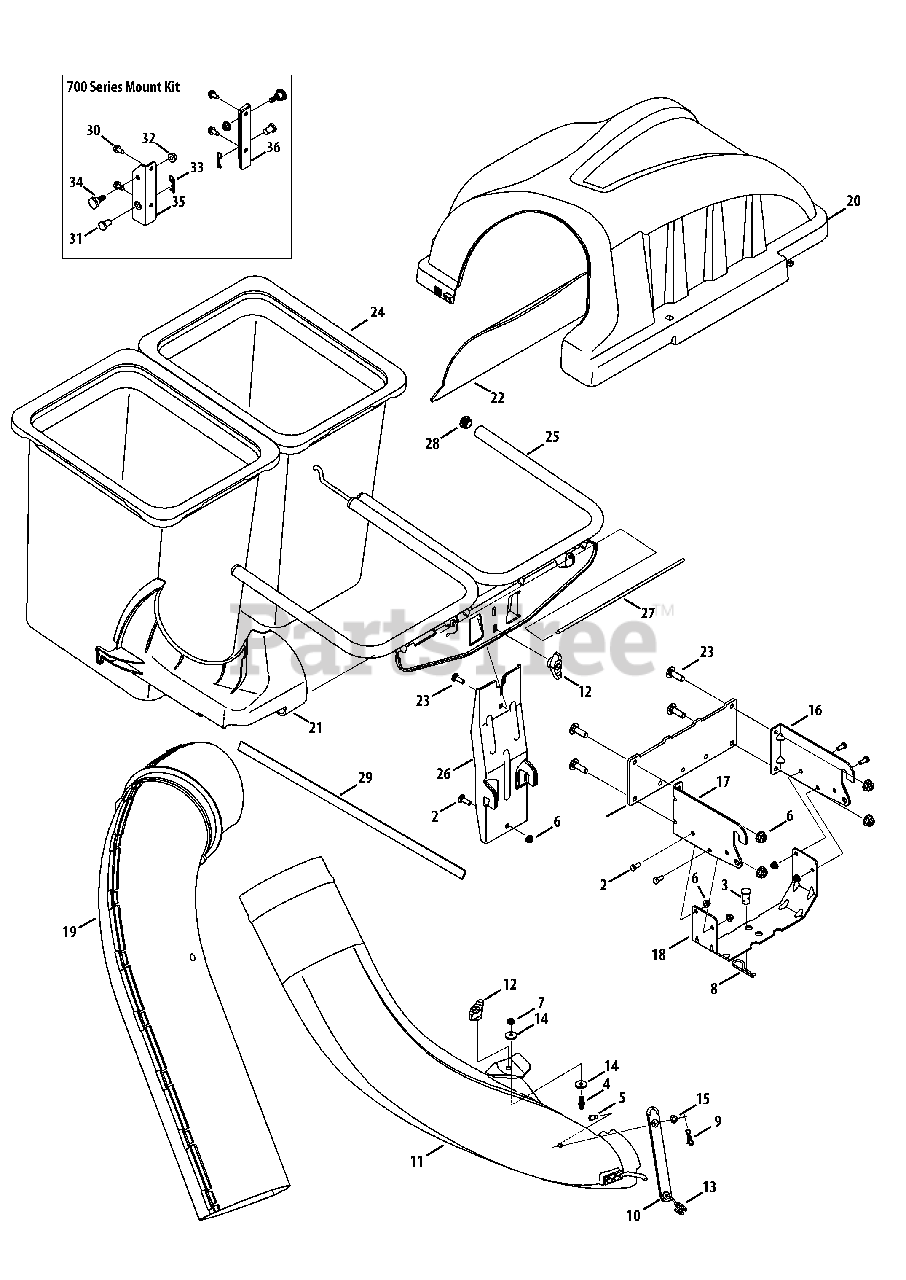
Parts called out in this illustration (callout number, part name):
1	Mounting Bracket Kit (Incl. ref. 16, 17)
2	Hex Head Screw, 5/16-18 x .75"
3	Clevis Pin, .62" Dia.
4	Attachment Pin, 1/4 x 0.66 Lg.
5	Clevis Pin, 5/16 x .75 Lg.
6	Flange Lock Nut, 5/16-18
7	Flange Lock Nut, 1/4-20
8	Internal Cotter Pin, .148 x 3.00
9	Bow-Tie Cotter Pin, 72
10	Chute Strap, 6.00 Lg.
11	Chute, Lower
11	Chute Rod, Lower
11	Screw-1/4-20 X .62
12	Wing Knob, 5/16-18
13	Torsion Spring Hook
14	Flat Washer, .265 x .938 x .120
15	Flat Washer, .344 x .62 x .033
16	Mounting Bracket, LH
17	Mounting Bracket, RH
18	Universal Bracket Support
19	Upper Discharge Chute
20	Double Bagger Cover Assembly
21	Upper Chute Support
22	Bagger Cover Screen
23	Carriage Screw, 5/16-18 x 1.00"
24	Grass-bag Assembly
25	Double Bag Support Assembly
26	Vertical Support Bracket
27	Cover Hinge Pin
28	End Plug
29	Self-Adhesive Foam Strip
30	Tap Screw, 5/16-18 x .750
31	Clevis Pin
32	Flange Lock Nut, 3/8-16
33	Click Pin, .092 x 1.64 Lg.
34	Shoulder Screw, .625 x .412
35	Mounting Bracket, RH
36	Mounting Bracket, LH
